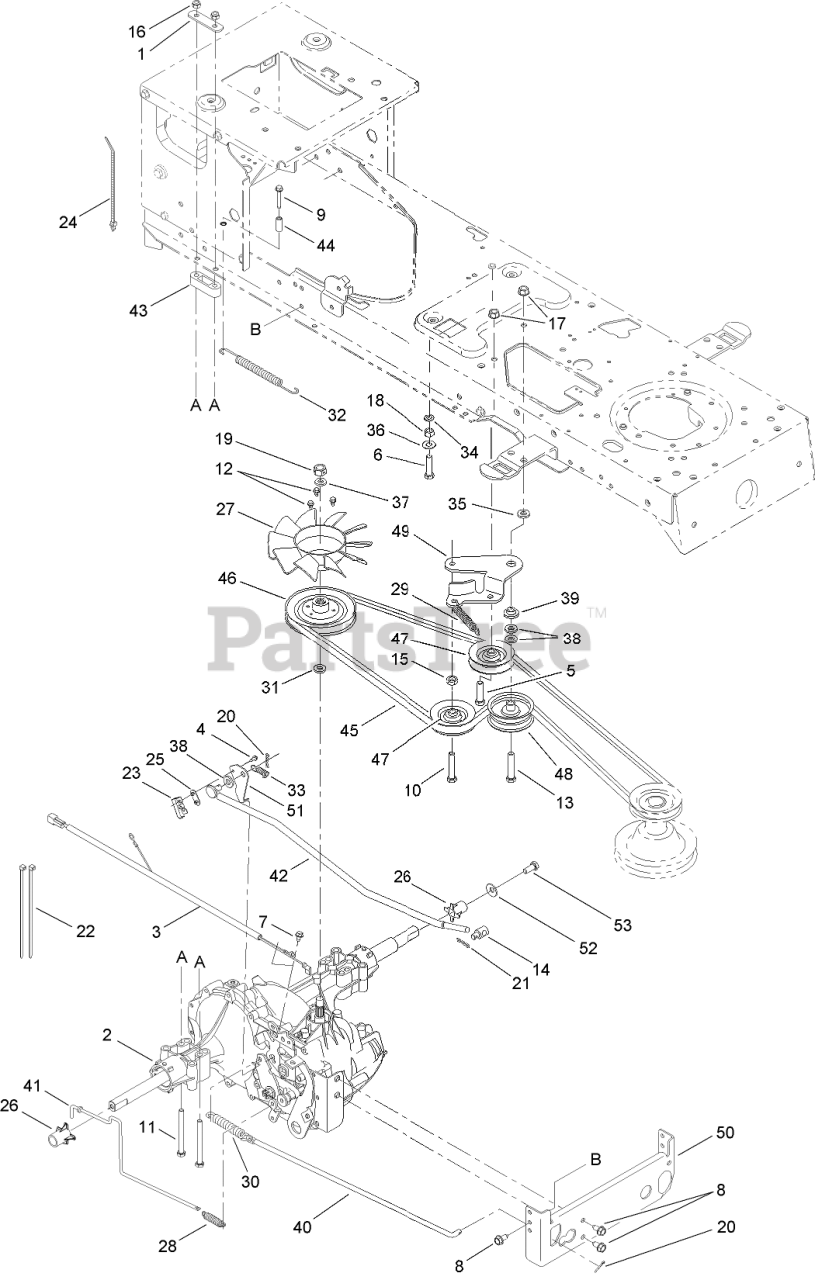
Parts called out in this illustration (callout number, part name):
1	BRACKET-MOUNTING, TRANSMISSION
2	HYDRO TRANSMISSION ASM
3	HARNESS ASM
4	SCREW-HWHTF
5	SCREW-HHFTF
6	SCREW-HH
7	SCREW-TAP
8	SCREW-HH, TAP
9	SCREW-HWH
10	SCREW-TAP
11	SCREW-HH
12	SCREW-HH, TAP
13	SCREW-HH
14	FERRULE
15	NUT-JAM
16	NUT-LOCK, FLANGE
17	NUT-LOCK, FLANGE
18	NUT-HEX
19	NUT-HEX
20	PIN-COTTER
21	PIN-COTTER
22	TIE-CABLE
23	SWITCH-SPRING, SHORT
24	TIE-CABLE
25	PLATE-INSULATOR
26	SLEEVE
27	FAN-BLADE, 10
28	SPRING-EXTENSION
29	SPRING-EXTENSION
30	SPRING-EXTENSION
31	RING-WIRE
32	SPRING-EXTENSION
33	SPRING-EXTENSION
34	WASHER-LOCK
35	WASHER-FLAT
36	WASHER-FLAT
37	WASHER-LOCK
38	WASHER-FLAT
39	SPACER-SHOULDER
40	ROD-BRAKE
41	ROD-HYDRO
42	ROD-CONTROL
43	SPACER-TRANSAXLE
44	SPACER
45	BELT-V, TYPE
46	PULLEY-INPUT
47	PULLEY-IDLER, V-TYPE
48	PULLEY-IDLER, FLAT
49	BRACKET-IDLER, CENTER DOUBLE
50	BRACKET-TORQ, TRANSMISSION
51	BRACKET-ACTUATOR
52	WASHER-BELL
53	SCREW-HH
